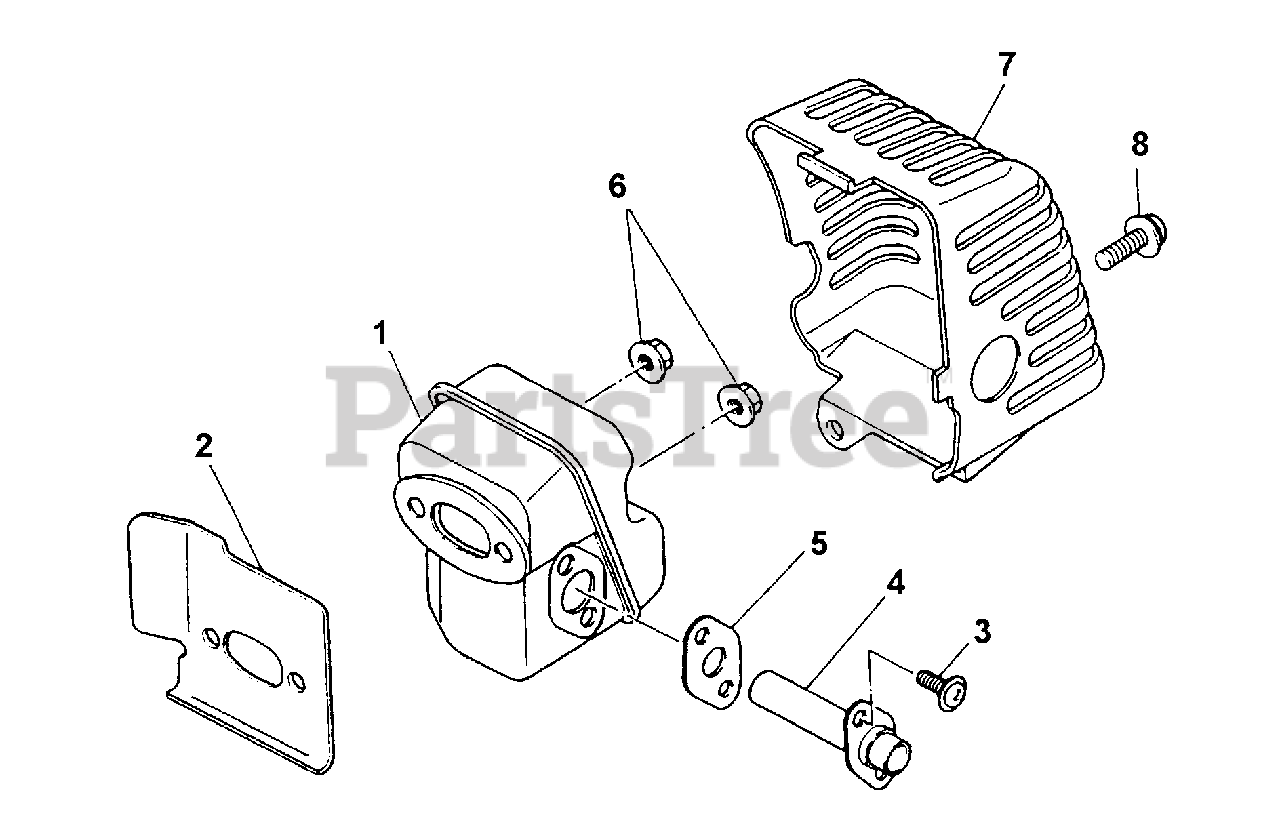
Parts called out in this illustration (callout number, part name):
1	MUFFLER ASSY
2	GASKET, MUFFLER
3	SCREW & WASHER
4	TAIL PIPE
5	GASKET, TAIL PIPE
6	NUT, FLANGE
7	COVER, MUFFLER
8	SCREW & WASHER
